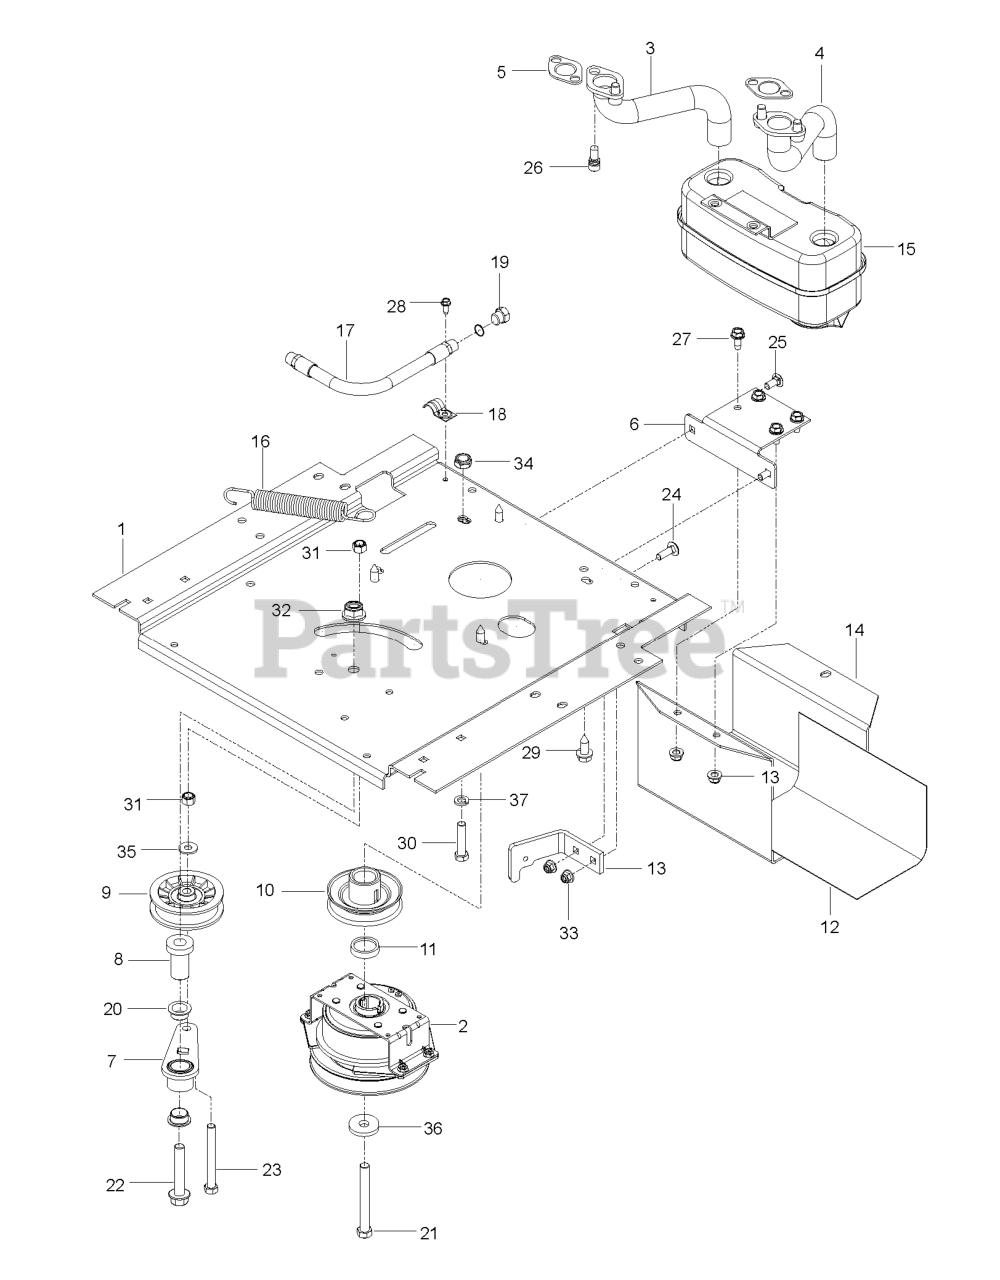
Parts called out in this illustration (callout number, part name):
1	PLATE.ENGINE.PNT.23"FRAME.EDIP
2	CLUTCH.OGURA.5.0PD.GT1.5A-EH07
3	EXHAUST.TUBE.MUFFLR.RH.VANG
4	EXHAUST.TUBE.MUFFLR.LH.VANG
5	GASKET.MUFF 806237 NOW 806425
6	BRACKET MUFFLER MS431BLK
7	ARM IDLER
8	SPINDLE.IDLER
9	PULLEY, IDLER RAKE & ZTR
10	PULLEY.ENGINE
11	SPACER.SPACER.625 W/OGURA.LCC
12	HEAT SHIELD
13	CLUTCH.STOP.OGURA LCC.BLACK
14	GUARD.MUFFLER.WO.TOW.HITCHX431
15	MUFFLER ASM TWIN
16	SPRING, DECK DRIVE
17	HOSE ASSY OIL DRAIN. VAN GUARD
19	PLUG OIL DRAIN
20	BEARING.FLANGED.PLASTIC.3/4ID
21	CLUTCH BOLT7/16-20X2.5 GR524HR
22	BOLT.FLANGE.1/2-13 X 2.75.GRD5
23	HCS 3/8-16X3-1/2 TAPBLT GR5 ZD
24	RHSNB 5/16C X 1
25	BOLT 5/16C X 3/4" CARRIAGE
26	SCREW.TUBE.MUFFLER.VANGUARD
27	SCREW.THDROL.5/16-18X3/4.TTY
28	SCR 1/4-20X5/8 HEX SELF TAP ZD
29	SCREW 3/8-16X1
30	BOLT, HCS 3/8-16X1-3/4
31	NUT 3/8-16 NYLOC
32	NUT, 1/2-13 HEX FLG NYLOC ZD
33	5/16-18 NYLOC FLANGE NUT
34	NUT HEX 3/8-16 NYLON, THIN
35	WASHER 5/16 FLAT
37	LOCKWASHER
